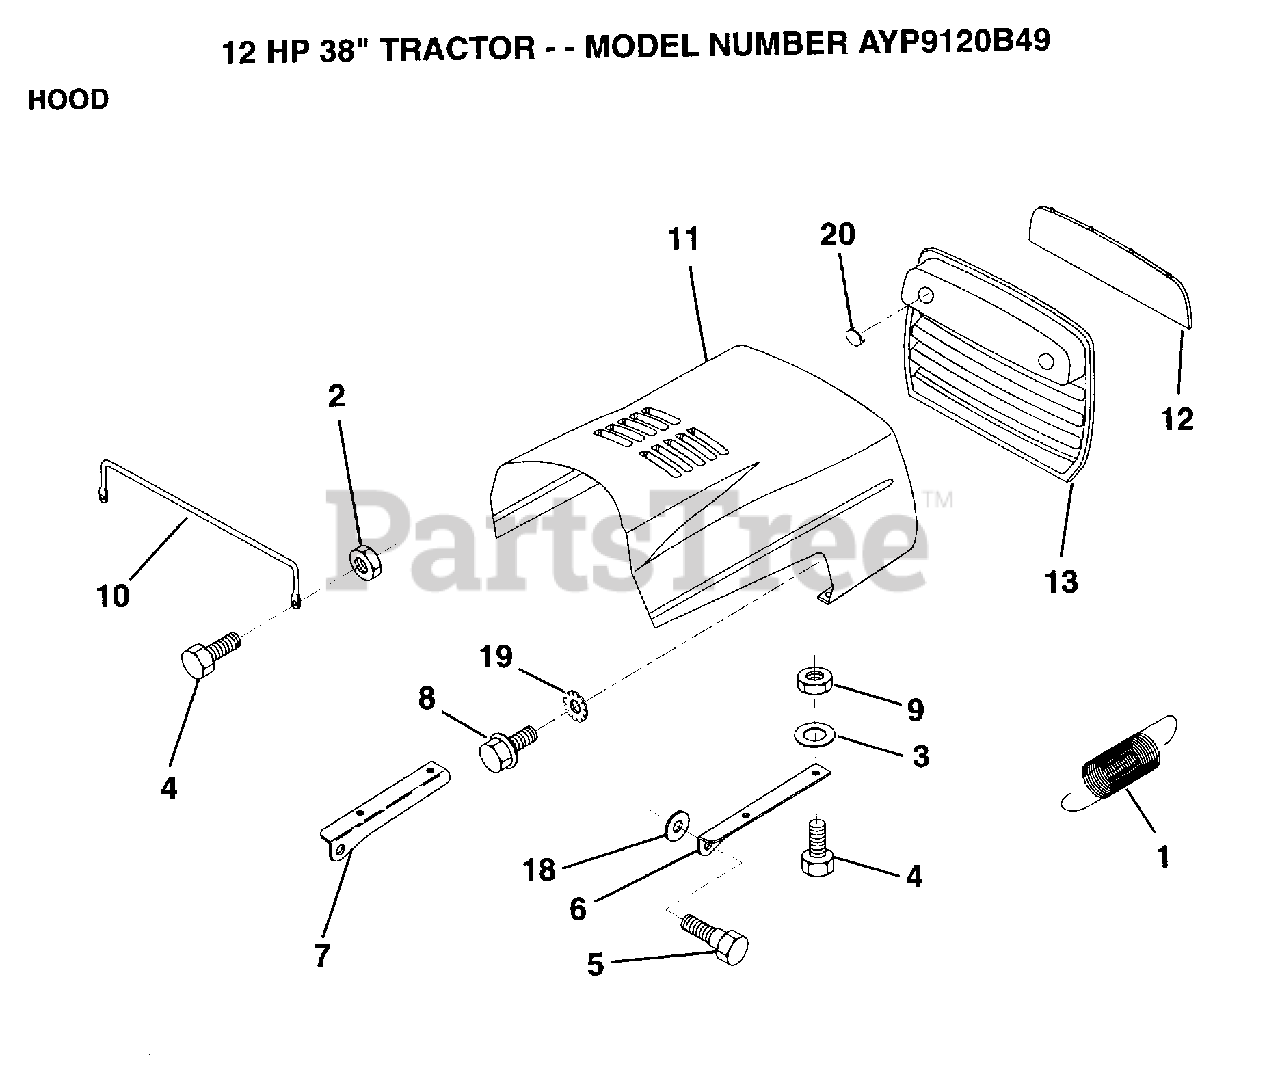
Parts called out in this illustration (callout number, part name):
1	EXT SPRING
2	NUT
3	WASHER
6	BRKT HOOD RH
7	BRKT HOOD LH
8	SCREW SLTD HXHD
9	NUT
10	"BRACE,HOOD"
11	HOOD
12	LENS
13	GRILL
18	WASHER
19	LOCKWASHER GT
